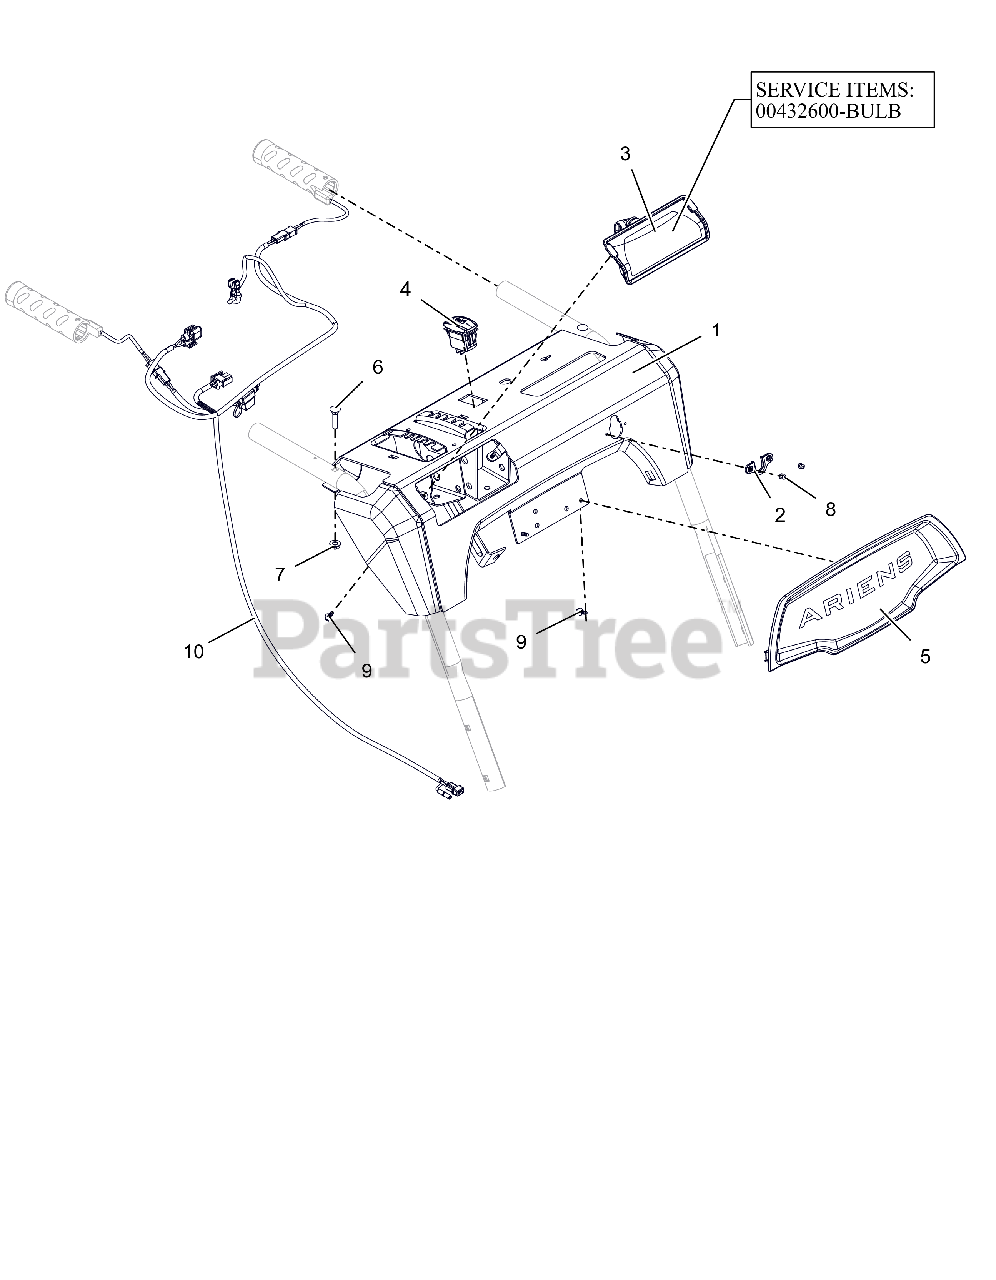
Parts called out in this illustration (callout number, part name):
1	PANEL, CONTROL-EFI QT W/DECAL
2	GROMMET, CABLE, QUICK TURN 2
3	HEADLIGHT ASY, HALO 20W 2SHOT
3	BULB, LIGHT-HALOGEN 20W
4	SWITCH,ROCKER SPST-ON/OFF
5	BEZEL, DASH - ARIENS LG DASH
6	BLT-RDHDXLSQNK.25-20X1.25 G5ZC
7	@NUT-LK-CTR-FLG .25-20 YWZC
8	RVT-POP #43 .125X.313 STL ZINC
9	SCR-TAP #10X.50 BOSS INDHXHD
10	HARNESS,LIGHT&WARMER - EFI
